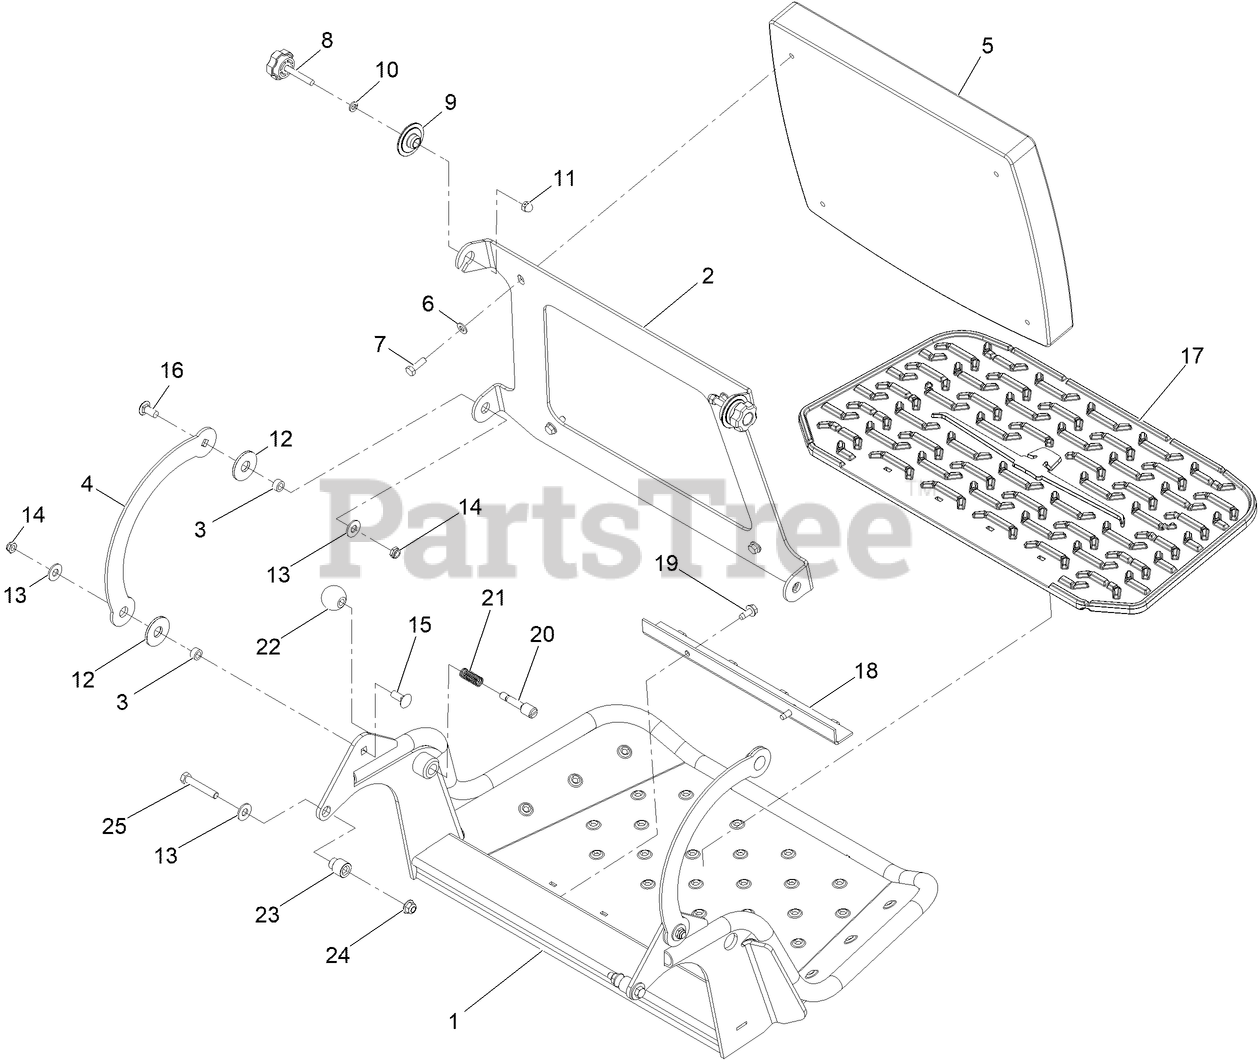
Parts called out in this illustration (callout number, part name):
2	HINGE-PAD
3	SPACER
5	CUSHION PAD ASM
6	WASHER-PLAIN
7	SCREW-HH
9	SLIDE-BUSHING
10	WASHER-LOCK
11	NUT-ACORN
12	WASHER-FRICTION, COMPOSIT
13	WASHER-FLAT
15	BOLT-CARR
16	SCREW-CARR
17	MAT-PLATFORM
18	CLAMP-SHIELD
19	Screw-HWH 5/16-18 X 3/4 Tf
20	PIN-LATCH
22	KNOB-BALL
23	BUSHING-FLANGED
24	NUT-HF, NI
25	SCREW-HH
